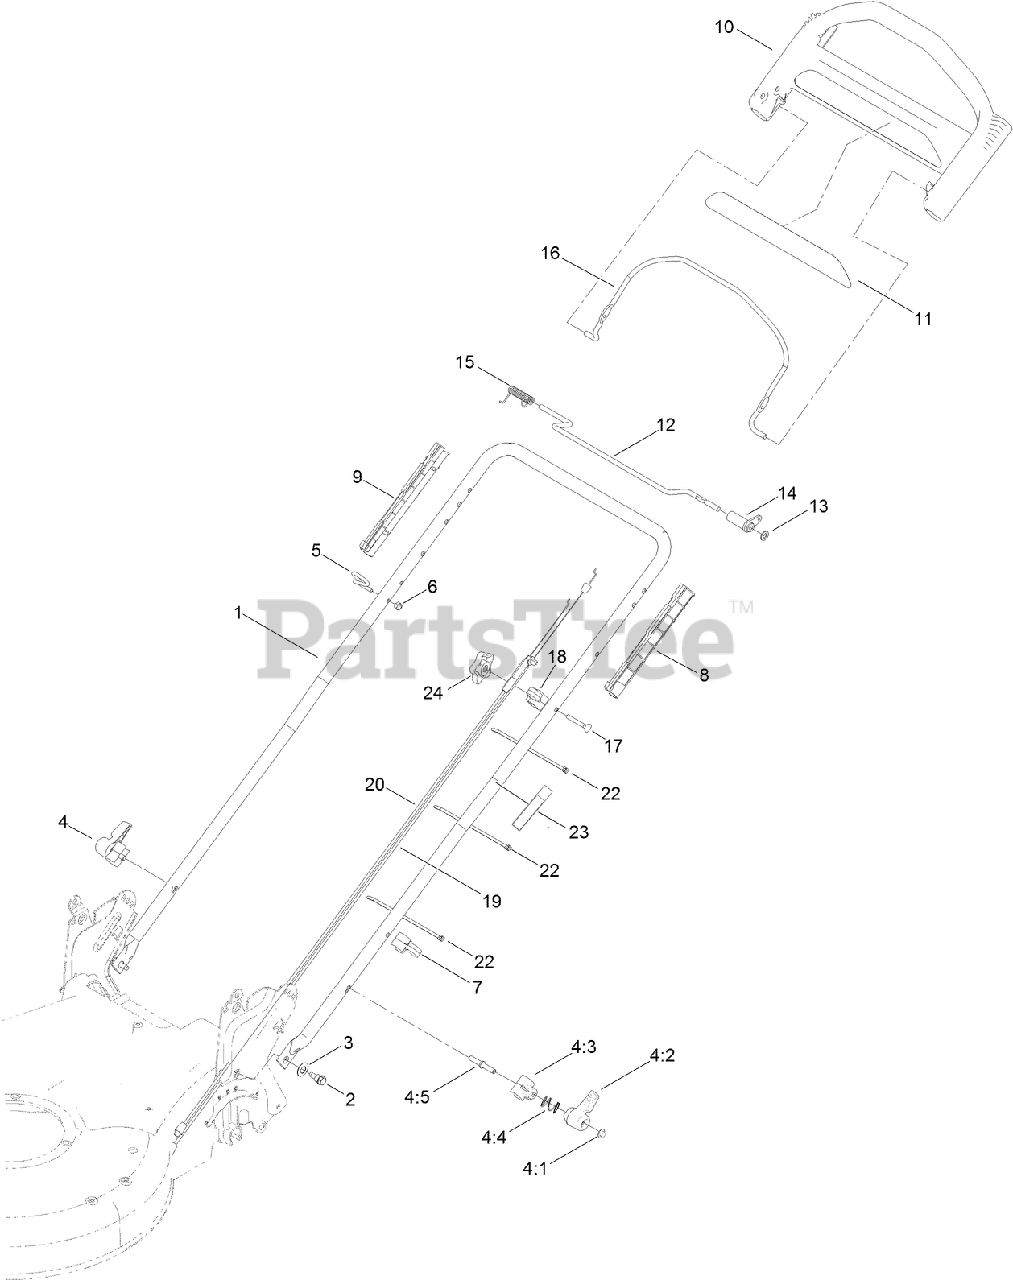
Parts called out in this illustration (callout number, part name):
2	BOLT-SHOULDER
3	WASHER-SPRING, CONICAL
4	QUICK RELEASE ASM
4:2	LEVER
4:3	ANCHOR-SPRING
4:4	SPRING-COMPRESSION
4:5	ROD-RELEASE
5	GUIDE-ROPE
6	NUT-LOCK, NI
7	GUIDE-CABLE
8	GUIDE-LH
9	GUIDE-RH
10	HANDLE-CONTROL
13	WASHER-PLAIN
14	LEVER-TRACTION
17	SCREW
19	CABLE-TRACTION
20	CABLE-BRAKE
22	TIE-CABLE
24	KNOB-HANDLE, LOCKING
